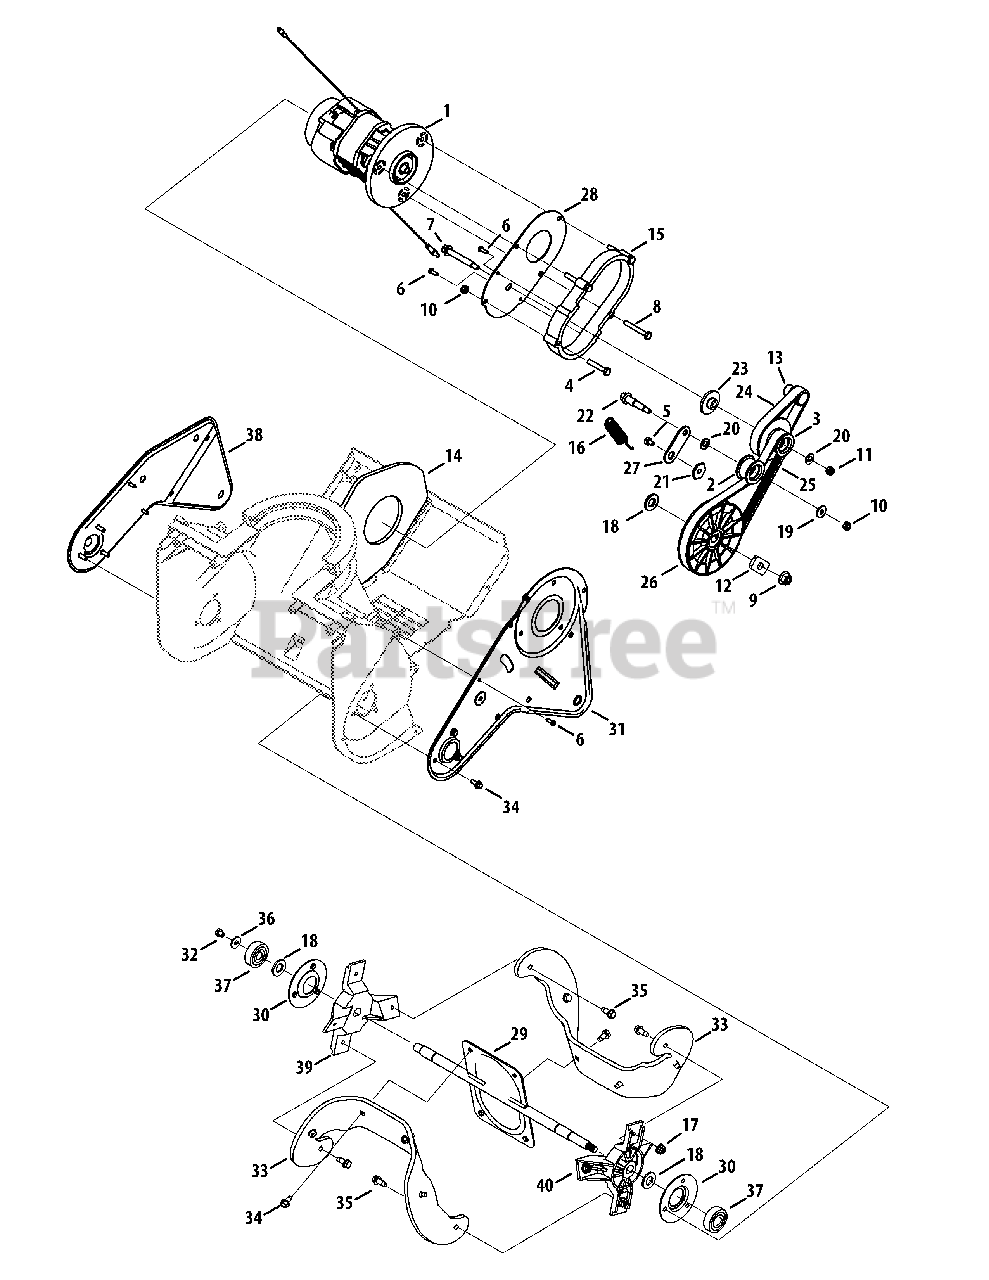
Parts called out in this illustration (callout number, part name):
1	Motor Assembly (Incl. Ref 13)
2	Pulley Assembly, Idler
3	Pulley Assembly
4	Screw, M6-1, 35.00
5	Screw, Hex Screw, M6 x 8mm
6	Screw, Tap, M4.2 x 1.4 x 13
7	Screw, Hex Flange, M8-1.25, 60mm
8	Screw, M6-1, 45.00
9	Nut, Flange Lock, 3/8-16, Nylon
10	Nut, Hex Lock, M6-1
11	Nut, Hex Lock, M8-1.25, Nylon
12	Plate, Drive Pulley
13	Pulley, 5mm, 15 Tooth
14	Gasket, Foam
15	Spacer, Motor Mount
16	Extension Spring, Idler
17	Nut, Flange Lock, 1/4-20, Nylon
18	Washer, Flat, M12
19	Washer, Flat, 6.4 Id x 18 OD
20	Washer, Flat, 8.4 x 16 x 1.60
21	Spacer, Shoulder, Hex, M6
22	Screw, Shoulder
23	Spacer, 8.35 x 16 x 11.65
24	Belt, Sync
25	Belt, Poly, 6 Rib
26	Pulley, Auger, 6 Rib
27	Bracket, Idler
28	Plate, Motor Mount
29	Auger Shaft Assembly
30	Cover, Bearing
31	Outer Frame, LH
32	Screw, Hex Screw, M6 x 8mm
33	Paddle Auger, Rubber
34	Screw, Self-tapping, 1/4-20, 0.500
35	Screw, 1/4-10 x .75
36	Washer, Flat, 6.4 Idx18 OD
37	Bearing, Ball, 12 x 37 x 12
38	Outer Frame, RH
39	Bracket, Paddle, Mount, LH
40	Bracket, Paddle, Mount, RH
